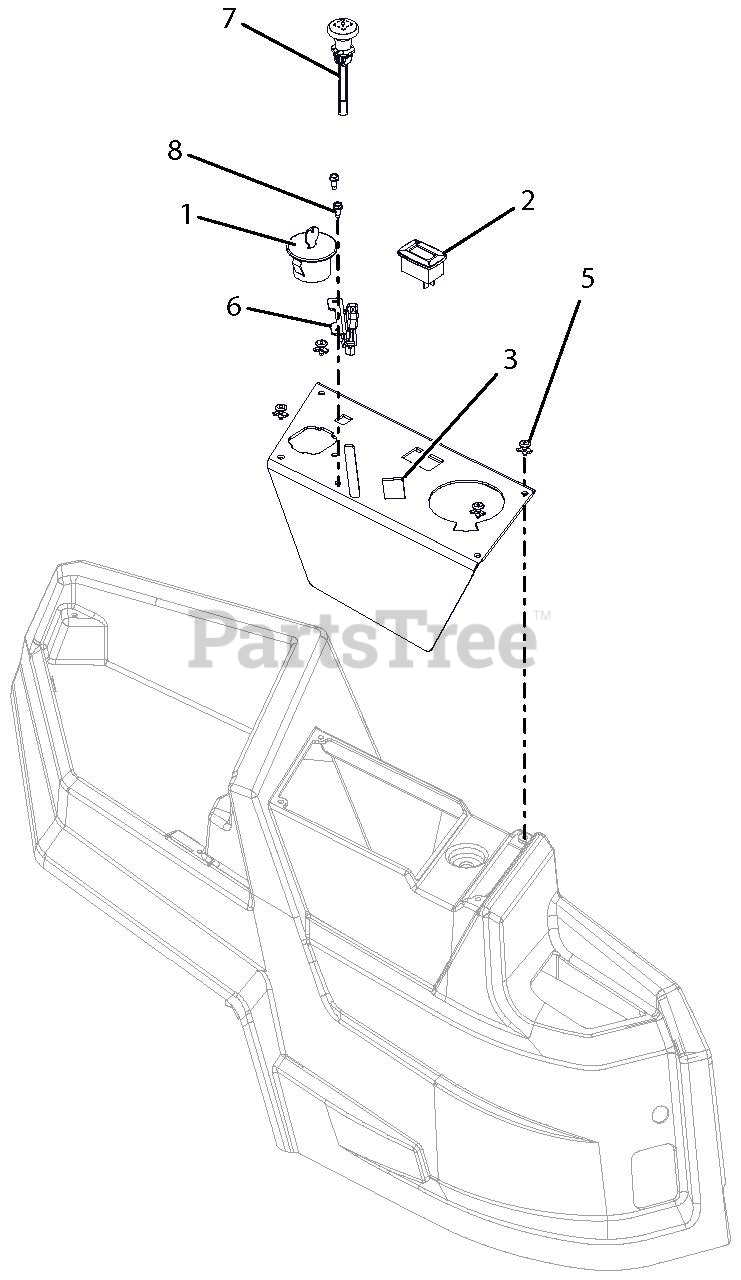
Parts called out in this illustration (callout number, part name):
1	KEY, 03290500 KEYSWITCH
1	KEYSWITCH-IGNITION 4 POS
2	METER, HOUR W/MAINTENANCE
3	PANEL, CONTROL
5	RIVET, PLASTIC .195 DIA.
6	CABLE - THROTTLE CONTROL
7	CABLE - CHOKE, SNAP-IN
8	@SCR-TAP 10-24X.50 HWH TR YWZC
